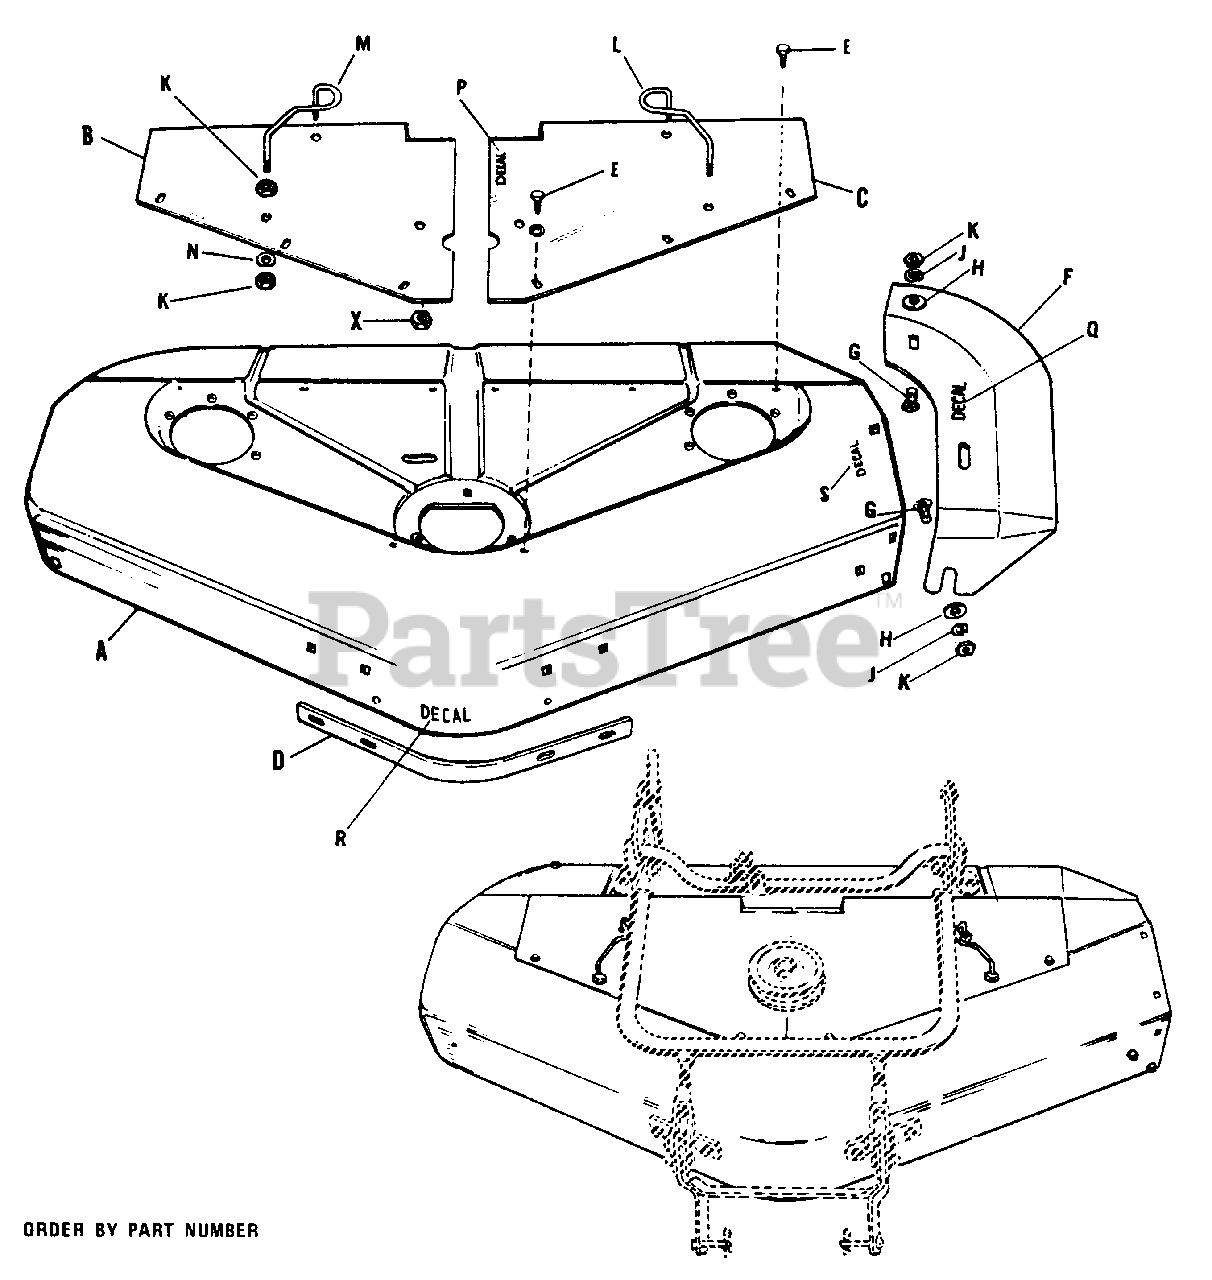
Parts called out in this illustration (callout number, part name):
A	Mower Housing
B	Cover, R.H.
C	Cover, L.H.
D	Bar, Reinforcing
E	Screw, Taptite, 1/4-20 x 3/8" lg.
F	Deflector
G	Bolt, 3/8-16 x 3/4 lg.
H	Washer-Special
J	Washer, Lock, 3/8"
K	Hex Nut, Full, 3/8-16
L	Guard, L.H.
M	Guard, R.H.
N	Washer, Plain, 3/8
T	Belt Guide Assembly
U	Hex Cap Screw, 5/16-18 x 3/4 lg.
V	Plain Washer 5/16
W	Lock Washer, 5/16
X	Nut Retainer
